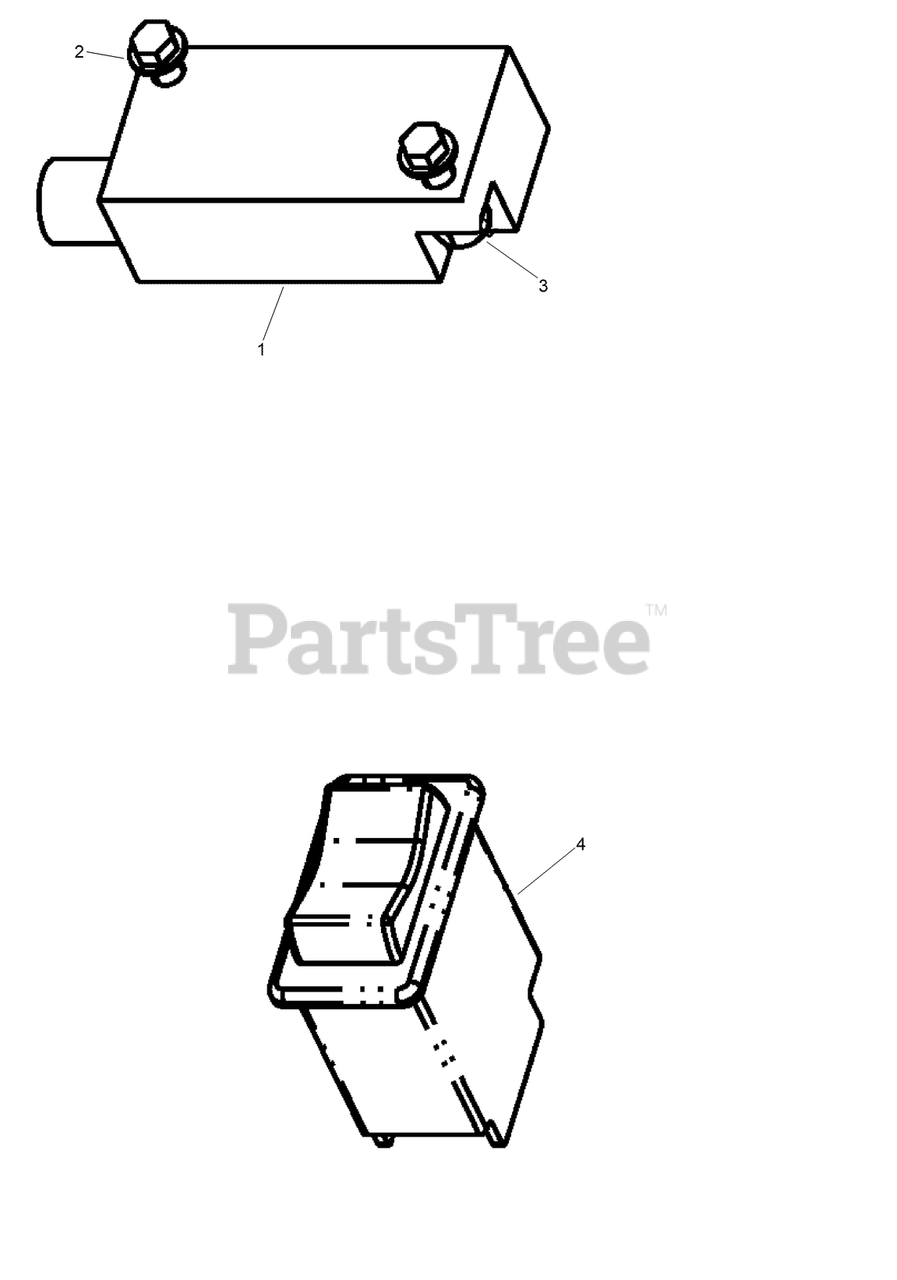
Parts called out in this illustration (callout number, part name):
1	SENSOR - Level
2	SCREW - Hex Wshr Hd # 8 - 32 x 0.75 ZND
3	NUT - Prev Trq # 8 GRB CAD Insert
4	SWITCH-ROCKER, 2 POLE (ON/OFF)
